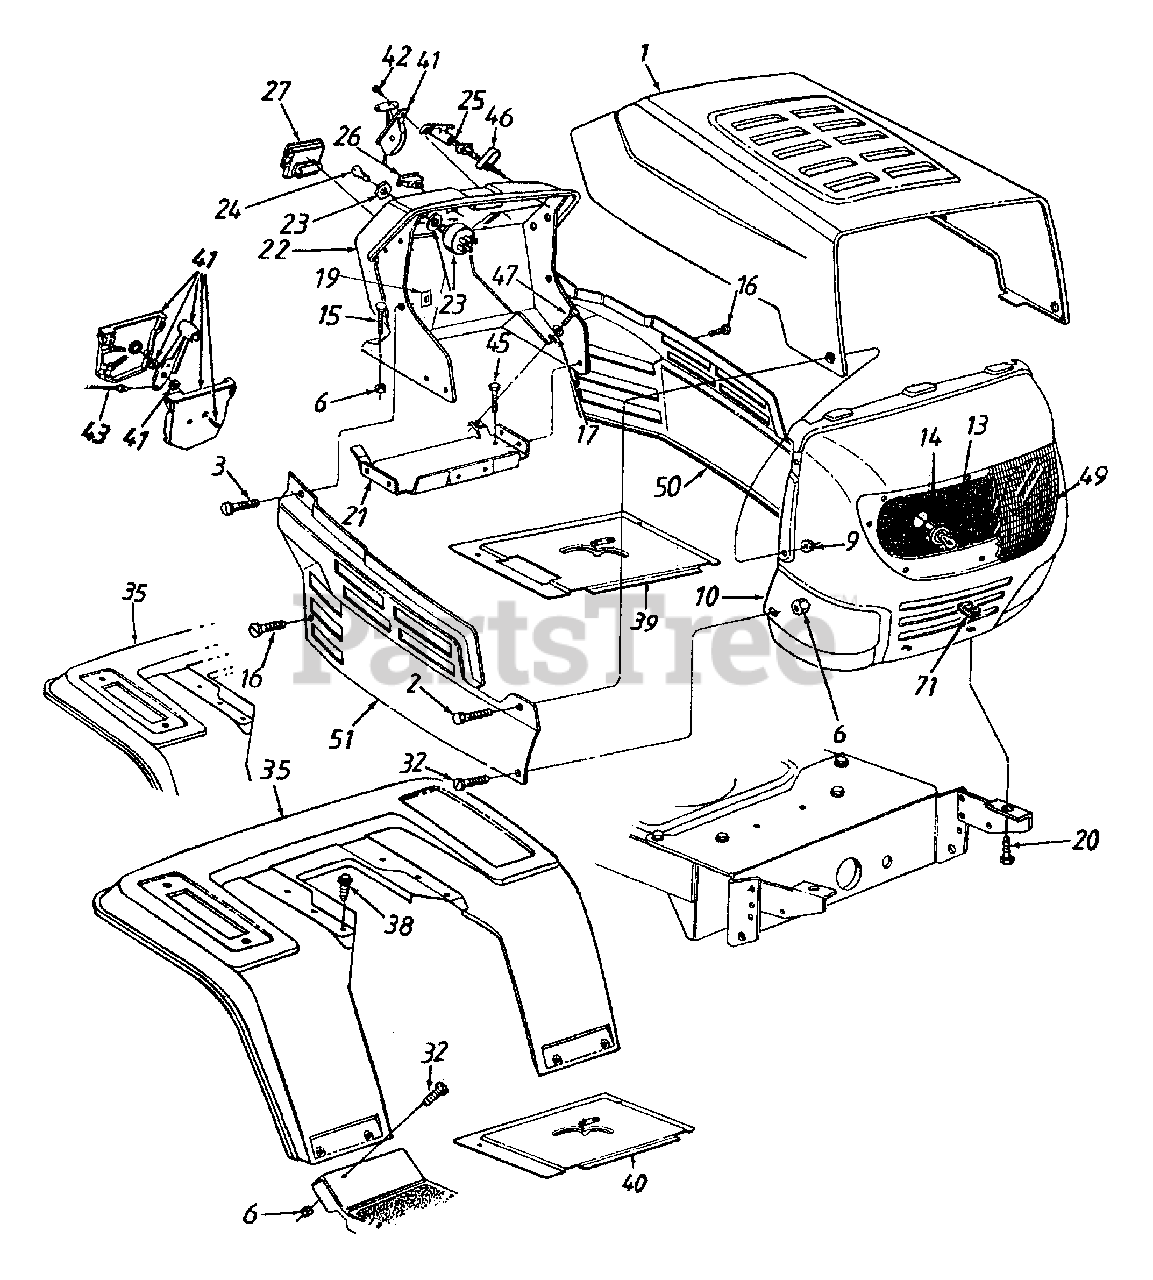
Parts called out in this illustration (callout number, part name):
3	Pan Hd. Scr. 1/4-20 x .75" Lg.
6	Hex Nut 1/4-20 Thd.
9	Flange L-Nut 1/4-20 Thd.
13	Lamp
14	Socket
15	Carriage Bolt 1/4-20 x .75" Lg.
16	Hex Wash. Hd. TT-Tap Scr. 1/4-20
17	Fl-Wash 281" I.D. x .73" O.D.
19	Speed Nut 1/4-20 Thd.
20	Hex Bolt 5/16-18 x 1" Lg. (Gr.5)
23	Ignition Switch
24	Ignition Key
25	Choke Control 23" Lg.
26	Light Switch
27	Ammeter
41	Throttle Box Ass'y.
42	Truss Mach. AB-Tap Scr. #10 x .5"
43	Throttle Control Wire 18.5" Lg.
45	Hex Wash. Hd. B-Tap Scr. 5/16-18
46	Choke Retainer
47	Hex TT Tap Scr. 1/4-20 x.75"Lg.
49	Lens
